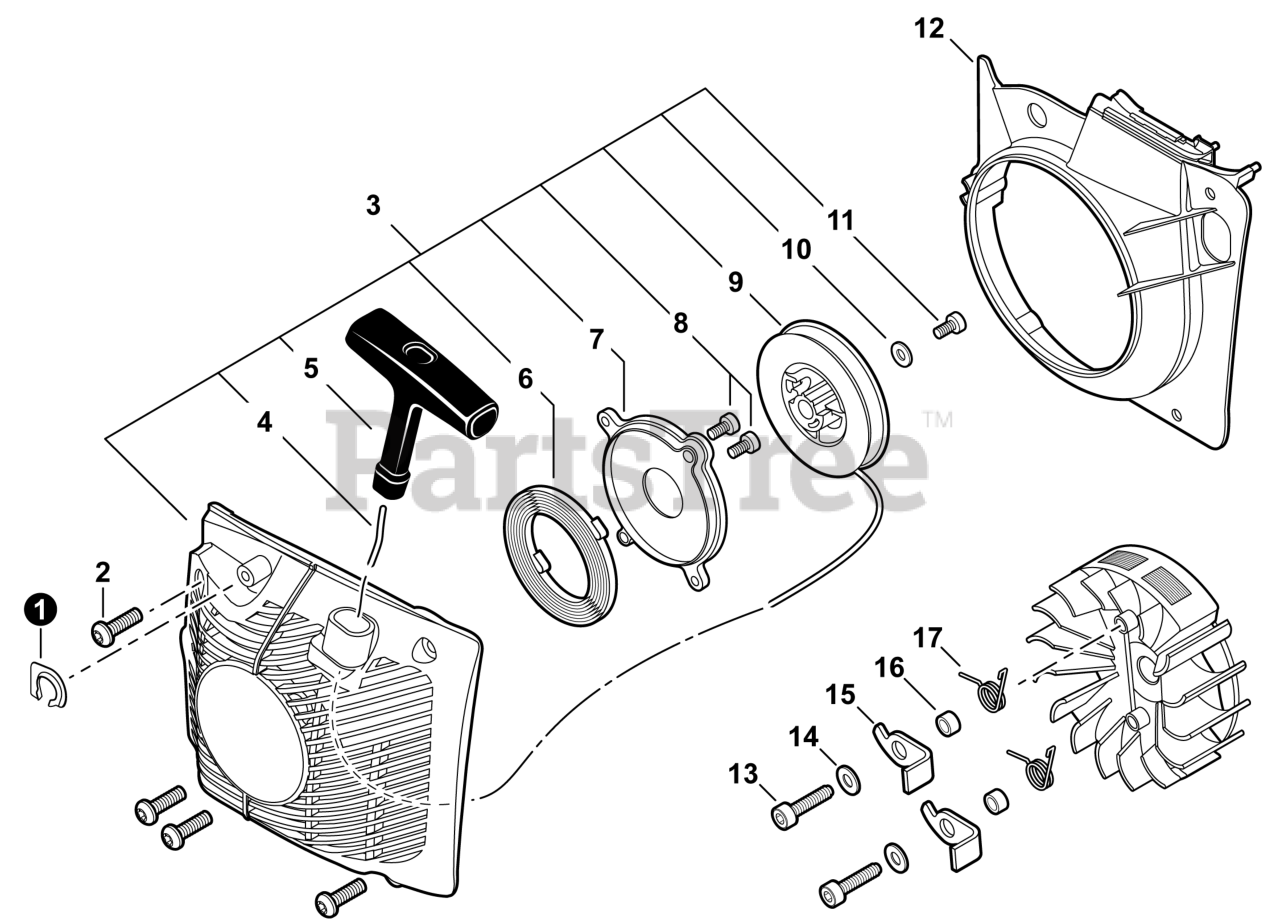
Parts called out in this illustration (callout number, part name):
1	PLATE, EYE
2	BOLT, TORX 5×20
3	STARTER ASSY, RECOIL
4	ROPE, STARTER Ø4×950
5	GRIP, STARTER
6	SPRING, RECOIL
7	PLATE, STARTER
8	BOLT, TORX 4×12
9	REEL, ROPE
10	WASHER 5.2×16×1.0
11	BOLT, TORX 5×10
12	COVER, FAN
13	BOLT, TORX 5×16
14	WASHER 5.5×12×0.8
15	PAWL, STARTER
16	SPACER 5.2×8×2.1
17	SPRING, TORSION
